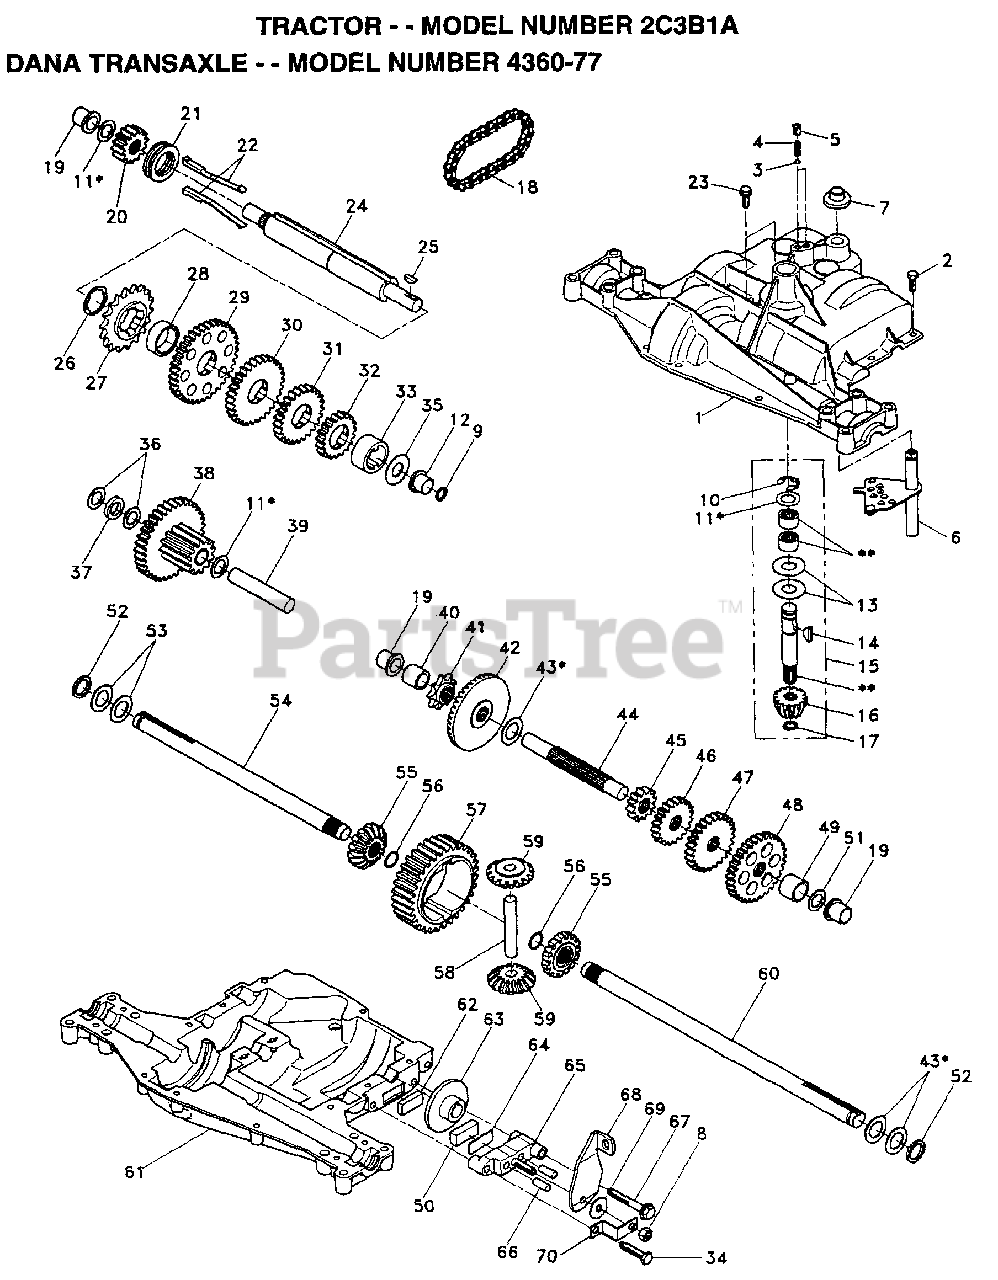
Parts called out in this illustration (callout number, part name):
1	HOUSING UPPER TRN
4	SPRING, DETENT LT
5	SCREW-SET 3623
6	KIT SHIFTER ASM
7	SHIFTER BOOT
8	NUT.LOCK.5/16-24
9	SEAL OIL DANA5416
11	ASM KIT SHIM 4689
13	WASHER.PLAIN..632X1.38X.046
14	KEY WOODRUFF-DANA
15	AS KIT INPUT SHFT
17	RING,RETAINING LT(3624)
18	CHAIN,24 PTCH LT
19	BEARING.FLNG.5510
20	GEAR SPUR 14 TTH
21	COLLAR CLUTCH
22	ASM KIT CLTCH KEY
23	SCREW TAP W/SEAL
24	SHAFT INTERM DANA
25	WOODRUFF KEY
26	RING,RETAINING LT (3627)
27	SPROCKET 18T T
28	SPACER YT
29	GEAR SPUR 37 TTH
30	Gear, Spur, 30 Teeth
31	GEAR 25T LT
32	SPUR GEAR 19T
33	SPACER 1.133 X 1.50 X .750
34	Screw, Self-Tapping, Large 5/16-18 x 1.44
35	WASHER, PLAIN LT
36	WASHER 025
39	SHAFT IDLER
40	SPACER T
41	SPROCKET 9T LT
43	ASM KIT SHIM
44	SHAFT T
45	GEAR SPUR 12 TTH
46	Gear, Spur, 20 Teeth
47	GEAR, SPUR 25T LT
48	Gear, Spur, 31 Teeth
49	SPACER T
50	PUCK.FRICTION (7109)
51	WASHER 060
52	NEOPRENE WASHER
53	WASHER 031
56	RING,RETAINING LT
57	Gear, Spur, 32 Teeth
58	SHAFT T(3919)
60	Axle, R.H.
61	HOUSING LOWER TNS
62	PUCK T
63	BRAKE DISC.T (5809)
64	SPACER LT (3758)
65	Jaw, Brake
66	PIN.DOWEL 3843
69	WASHER LT (3760)
70	Bracket, Anti-Rotation
71	Grease
